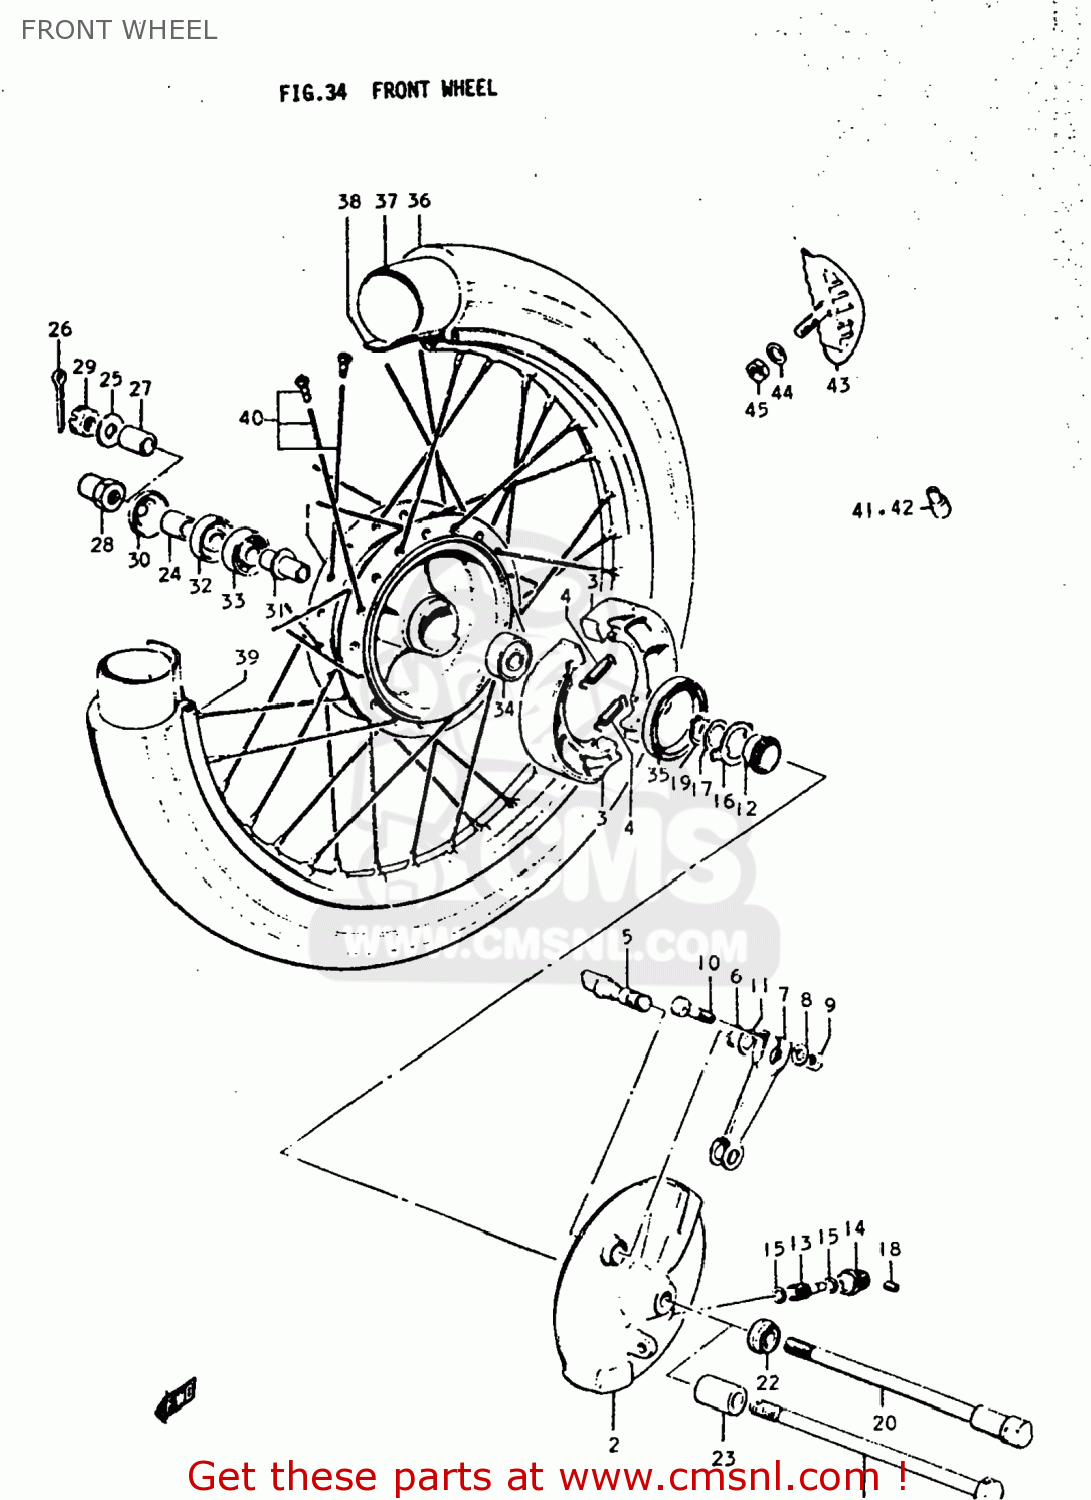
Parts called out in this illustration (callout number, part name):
1	HUB,FRONT
2	PANEL,FRONT HUB
3	SHOE,BRAKE
4	SPRING(L:34)
5	CAM,FR BRAKE
6	O RING(D:2.5,ID:11.4)
7	LEVER,FRONT BRAKE CAM
8	WASHER
9	NUT
10	BOLT
11	WASHER(12.5X20X1)
12	GEAR,SPEEDOMETER
13	PINION,SPEEDOMETER
14	BUSH,METER GEAR OUTER
15	WASHER (5.1X9X0.4)
16	DRIVER,SPEEDOMETER GEAR
17	WASHER(18.5X24X1)
18	SCREW
19	CIRCLIP
20	AXLE,FRONT
21	AXLE,FRONT
22	SPACER,FRONT AXLE,LEFT
23	SPACER (12X20X41)
24	SPACER(12X18X16.4)
25	WASHER
26	COTTER PIN
27	SPACER (12X20X44)
29	NUT 12MM
30	DUST SEAL,FRONT HUB DRUM
31	SPACER,FRONT HUB BEARING
32	OIL SEAL(17X38X5)
33	BEARING
34	BEARING, RH
35	SEAL,OIL(48X62X7)
36	TIRE,FRONT
37	TUBE 2.75-19 070-483MM
38	PROTECTOR,WHEEL,INNER
39	RIM,FRONT WHEEL
40	SPOKE SET,FRONT
41	BALANCER,WHEEL (50G)
42	BALANCER,WHEEL (30G)
43	STOPPER,BEAD
44	WASHER
45	NUT
